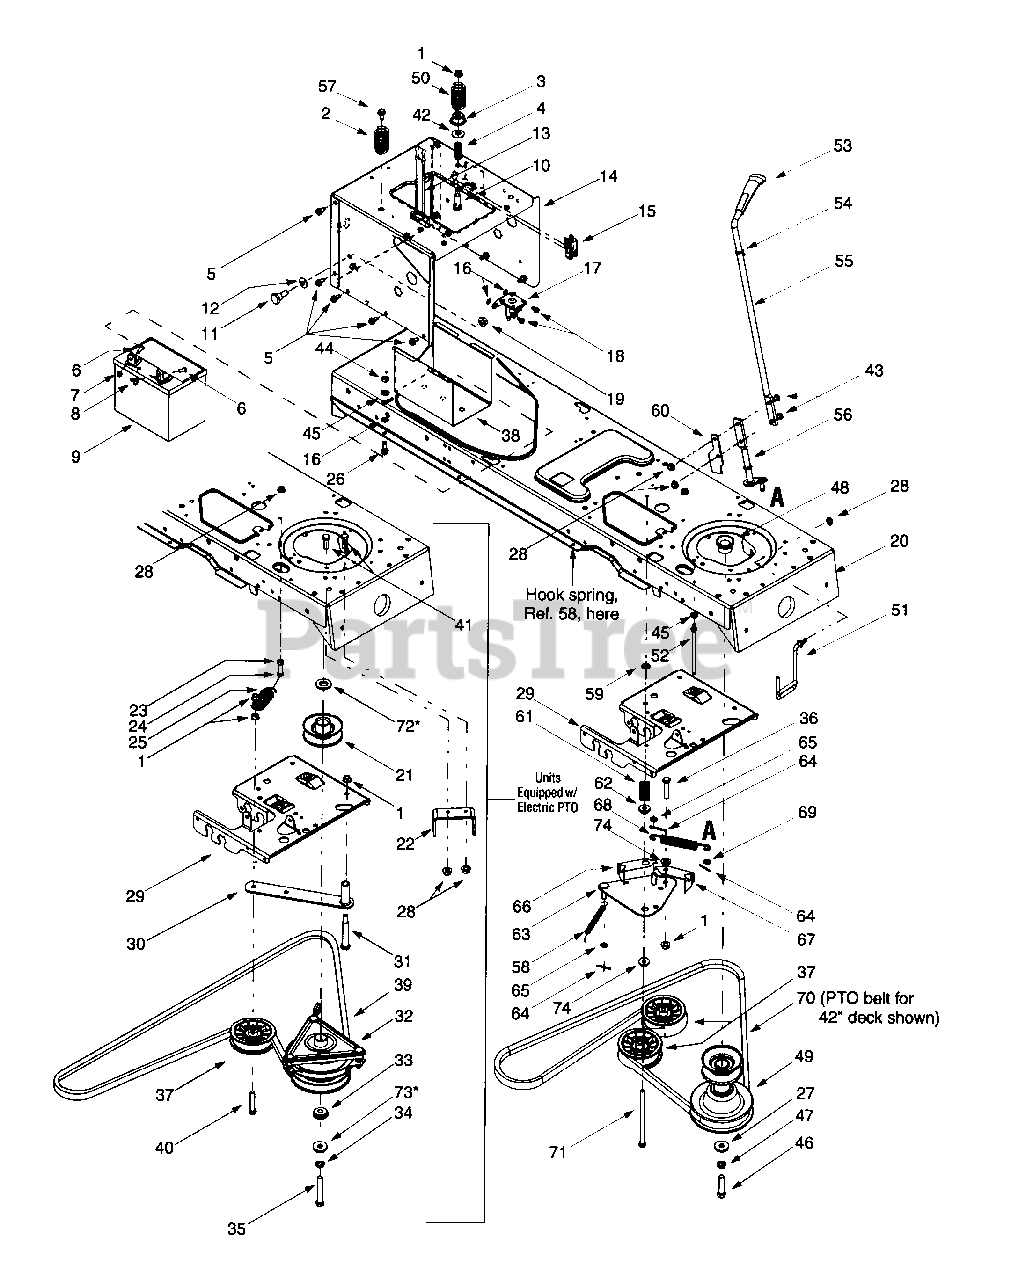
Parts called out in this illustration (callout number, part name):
1	Flange Lock Nut,3/8-16
2	Compression Spring, 1.31 x 3.0
3	Spacer Cup, 1.5 OD
4	Compression Spring, .66 OD x 1.5
5	Self-tapping Screw, 5/16-18 x .625
6	Hex Cap Screw, 1/4-20 x .62
7	Hex Sems Nut, 1/4-20
8	Wing Nut, 1/4-20
9	12-volt Battery, 270 CCA
10	Shoulder Screw, .5 x 1.25, 3/8-16
11	Shoulder Screw, .625 x .5, 7/16-20
12	Bell Washer, .45 x 1.0 x .062
13	Battery Strap
16	Lock Washer, 1/4
17	Solenoid, 12-Volt, 100 Amp
18	Self-tapping Screw, 1/4-20 x .5
19	Flange Lock Nut, 7/16-20
24	Hex Cap Screw, 5/16-18 x 1.75 (Grade 5)
25	Extension Spring, 1.2 OD x 3.638
26	Self-tapping Screw, 1/4-20 x .750
27	Flat Washer,.45 x 1.25x.164
28	Flange Lock Nut, 5/16-18
32	Electric PTO Clutch
33	Shoulder Spacer, 1.38 x .445 x .36
34	Lock Washer, 7/16
35	Hex Cap Screw, 7/16-20 x 3.25 (Grade 5)
36	Hex Cap Screw, 3/8-16 x 2.25 (Grade 5)
37	Flat Idler Pulley, 3.5 OD
39	PTO Belt (46-inch Decks w/ Electric PTO)
40	Hex Cap Screw, 3/8-16 x 2.0
41	Hex Cap Screw, 5/16-18 x .625
42	Bell Washer, .401 x .870 x .063
43	Hex Cap Screw, 5/16-18 x 1.0
44	Hex Nut, 1/4-20
45	Lock Washer, 5/16
46	Hex Cap Screw, 7/16-20 x 1.25
47	Lock Washer, 7/16
49	Engine Pulley
50	Extension Spring, 1.318 x 2.37
51	Belt Guard
52	Keeper Pin
53	PTO Knob
54	Flat Washer, .510 x .750 x .033
55	PTO Handle
56	PTO Lever
57	Self-tapping Screw,15/16-18 x .875
58	Extension Spring, .5 x 6.0
59	Push Nut, 3/8
61	Spacer, 3/8 x 1.54
62	Shoulder Spacer
64	Cotter Pin, 1/8 x 1.25
65	Flat Washer, .385 x .62 x .063
66	Belt Guard
67	Belt Guard
68	Extension Spring, .75 x 6.75 LG
69	Flat Washer, .344 x .688 x .065 Manual PTO
70	PTO Belt (42-inch Decks w/ Manual PTO)Single Belt, Design
70	PTO Belt (42-inch Decks w/Manual PTO) 2 Belt Design
70	PTO Belt (46-inch Decks w/ Manual PTO)
71	Hex Cap Screw, 3/8-16 x 5.5
72	Flat Washer, 1.031 x 1.62 x .095
73	Flat Washer, .45 x 1.25 x .17
74	Flat Washer, .407 x .812 x .135
75	Flat Washer, .395 x 1.12 x .10
